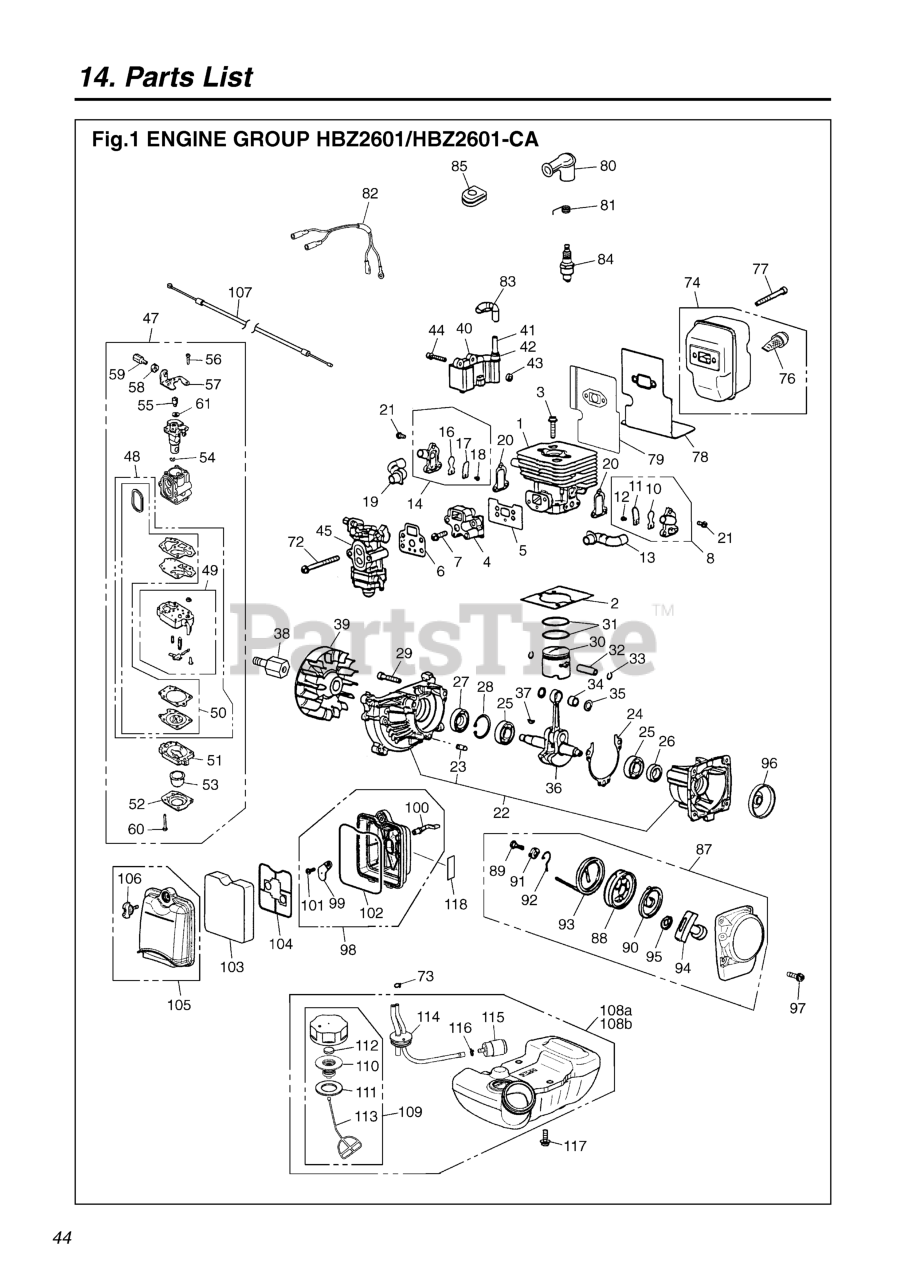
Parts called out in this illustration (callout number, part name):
1	CYLINDER
2	GASKET
3	BOLT TORX
4	INSULATOR
5	GASKET
6	GASKET
7	BOLT TORX
8	REEDVALVE ASSY S
10	REEDVALVE
11	STOPPER
12	SCREW
13	PIPE, AIR S
14	REEDVALVE ASSY F
16	REEDVALVE
17	STOPPER
18	SCREW
19	PIPE, AIR F
20	GASKET
21	BOLT
22	CRANKCASE COMP
23	PIN
24	GASKET
25	BEARING
26	SEAL
27	SEAL
28	RING
29	BOLT TORX
30	PISTON
31	RING
32	PIN
33	RING
34	BEARING
35	WASHER
36	CRANKSHAFT COMP
37	KEY
38	EXTENSION
39	ROTOR
40	COIL ASSY
41	CORD
42	CAP
43	SPACER
44	BOLT TORX
47	CARBURETOR ASSY
48	REBUILD KIT
49	BODY ASSY
50	GASKET KIT
51	BODY
52	COVER
53	PUMP
54	RING
55	SWIVEL
56	SCREW
58	NUT
59	SCREW
60	SCREW
61	WASHER
72	SCREW
73	CLIP
74	MUFFLER ASSY
76	ARRESTER
77	BOLT TORX
78	GASKET
79	PLATE
81	SPRING
82	CORD COMP
83	TUBE
84	SPARK PLUG
85	GROMMET
87	RECOIL ASSY
88	REEL
89	SCREW
90	SPRING
91	COLLAR
92	ARM
93	ROPE
94	KNOB
95	PLATE
96	PULLEY
97	BOLT TORX
98	BODY ASSY
99	PLATE, CHOKE
100	LEVER
101	SCREW
103	ELEMENT
104	PLATE
105	COVER ASSY
106	KNOB
107	CABLE
108A	TANK ASSY
109	CAP ASSY
110	HOLDER ASSY
111	PACKING
112	FILTER
113	STOPPER
114	PIPE COMP
115	FILTER ASSY
116	CLIP
117	BOLT TORX
118	LABEL
